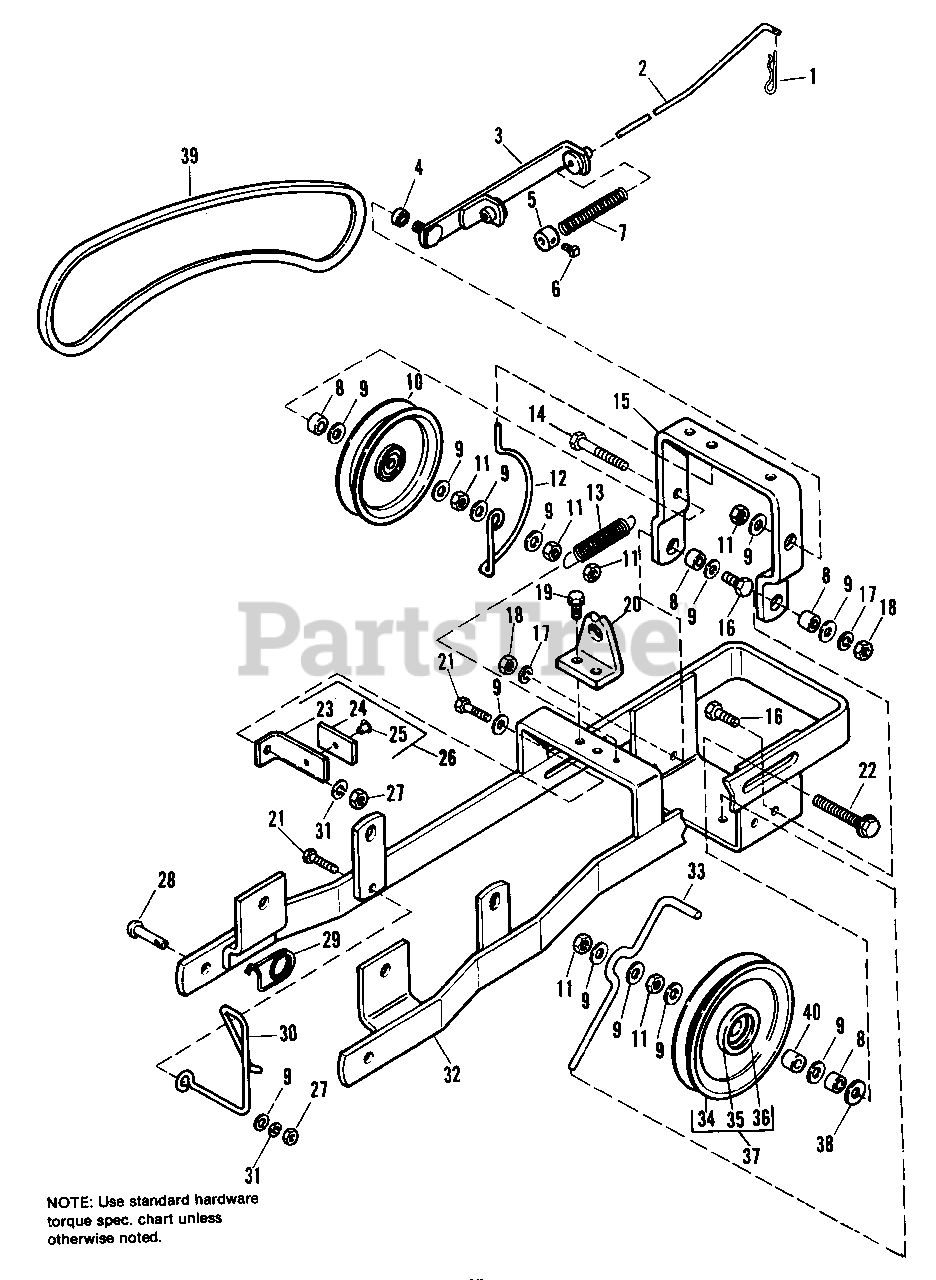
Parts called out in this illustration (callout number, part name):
1	CLIP, Spring
3	ROD GUIDE ASSY.
5	COLLAR, Set
6	SETSCREW, 1/4-20 x 3/8
9	WASHER, 5/16
11	LOCKNUT, Hex, Jam, 3/8-16
13	SPRING, Tension
14	CAPSCREW, Hex, 3/8-16 x 2-1/2
15	BRACKET, Pivot
16	CAPSCREW, Hex, 3/8-16 x 1-1/4
17	LOCKWASHER, 3/8
18	NUT, 3/8-16
19	SCREW, Taptite, 5/16- 18 x 3/4
21	CAPSCREW, Hex, 5/16-18 x 1-1/4
22	SCREW, Whizlock, 3/8-16 x 23
23	BRACKET, Brake
26	BRACKET ASSY., Brake (Incl. Ref. Nos. 23, 24 & 25)
27	NUT, Hex, Full, 5/16-18
29	CLIP, Spring, Safety
31	LOCKWASHER, 5/16
32	PUSH BAR ASSY.
35	RING, Retaining
37	PULLEY ASSY., w/Bearings (Incl. Ref. Nos. 34, 35 & 36)
38	WASHER, 13/32 x 1 x 10 Ga.
39	BELT, V (Drive)
